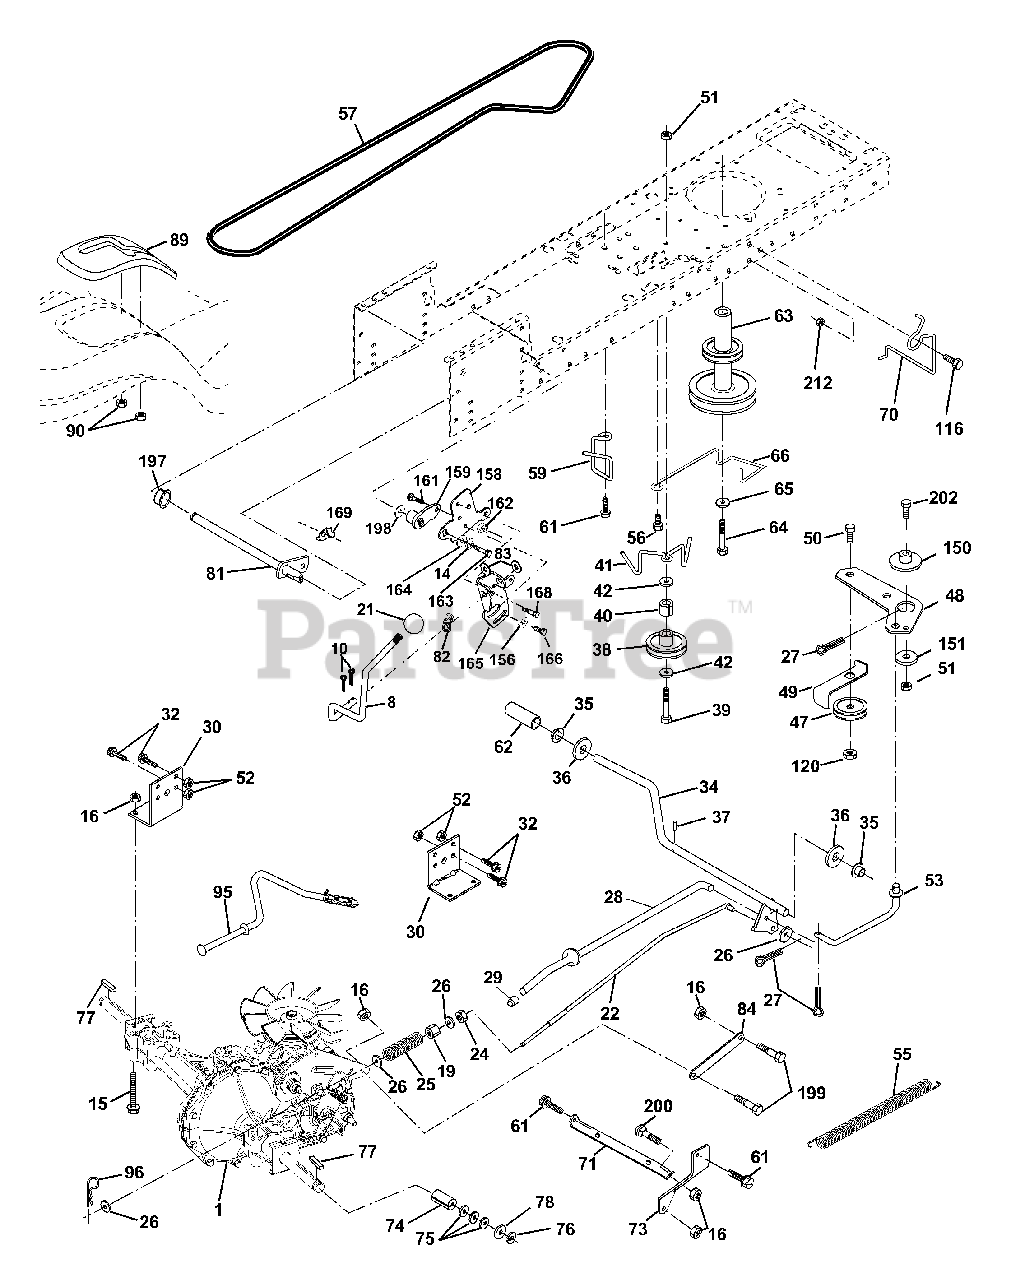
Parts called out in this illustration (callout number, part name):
8	Rod Shift Fender STLT
10	Pin Cotter 1/8 x 1 CAD
14	Washer Lock Hvy Helical 1/4
15	Bolt Hex Flg Hd 5/16-18 X Gr.5
16	Nut Lock Hex W/Ins. 5/16-18 Unc P
19	Nut Lock Hex W/Wsh 3/8-16 Unc
21	Knob, Duckhead
22	Rod, Brake Hydro
24	Nut
25	Spring, Brake Rod
26	Washer
27	Pin Cotter 1/8 x 3/4 CAD.
28	Rod, Parking Brake
29	Cap, Parking Brake
30	Bracket, Transaxle
32	Bolt Hex Hd 5/16-18 Unc x 3/4
34	Shaft, Foot Pedal
35	Bearing, Nylon
37	Pin, Roll
38	Pulley, Composite, Flat
39	Bolt Fin Hex 3/8-16 Unc x 2-3/4
40	Spacer, Split
41	Keeper, Belt Idler
42	Washer 13/32 x 13/16 x 12 Gauge
47	Pulley, Idler, V-Groove
48	Bellcrank Clutch Grnd Drv Stl
49	Retainer, Belt
50	Bolt Hex 3/8-16 Unc x 1-1/2
51	Nut Crownlock 3/8-16
52	Nut Crownlock 5/16-18
53	Link, Clutch
55	Spring, Return, Clutch
56	Vis 3/8-16 x 1
57	V-Belt, Ground Drive
59	Keeper, Center Span
61	Screw 3/8-16 x 3/4
62	Cover, Pedal
63	Pulley, Clutch Eng
64	Bolt Hex 7/16-20 x 4 Ga. 5
65	Washer
66	Keeper Belt Engine
70	Guide Belt Mower Drive RH
71	Strap Torque Lh Hydro
73	Strap Torque Rh Hydro
74	Spacer, Axle
75	Washer 25/32 x 1-1/4 x 16 Gauge
77	Key, Square
78	Washer 25/32 x 1-5/8 x 16 Gauge
81	Shaft Asm. Cross Hydro
82	Spring Torsion T/A
83	Washer 17/32 x 3/4 x 16 Ga.
84	Link Transaxle
89	Console, Shift
90	Nut Self-Thd wsh-Hd 1/4 Zinc
95	Control Asm Bypass Hydro
96	Retainer Spring 1" Zinc/Cad
116	Bolt 3/8-16 x 1
120	Nut Lock 3/8-16
150	Spacer Retainer
151	Washer 13/32 x 2 x 10 Ga.
156	Washer Srrtd 5/16 ID x 1.0 x .125 Tk
158	Bracket Shift Mount
159	Hub Tapered Flange Shift LT
161	Bolt Rdhd Sqnk 1/4-20 x 3/4 Gr. 5
162	Nut Crownlock 1/4-20 Unc
163	Bolt Hex Fin 1/4-20 unc x 1 Gr. 5
164	Washer 5/8 x .281 x 10 Ga
165	Bracket Pivot Lever
166	Screw 5/16-18 x 5/8 TT Yellow
168	Bolt Shoulder 5/16-18 x .561 TT
169	Plate Fastening Cross Shf. STLT/CRD
197	Nyliner Snap-In 5/8" ID
198	Washer Nyl 7/8 ID x .105 HYD CRD
199	Bolt Shoulder 5/16-18 Unc
200	Bolt Rdhd Sqnk 5/16-18 Unc x 1
202	Bolt Carr Sh 3/8-16 x 1-3/4 Gr. 5
212	Nut Hexflange Lock
